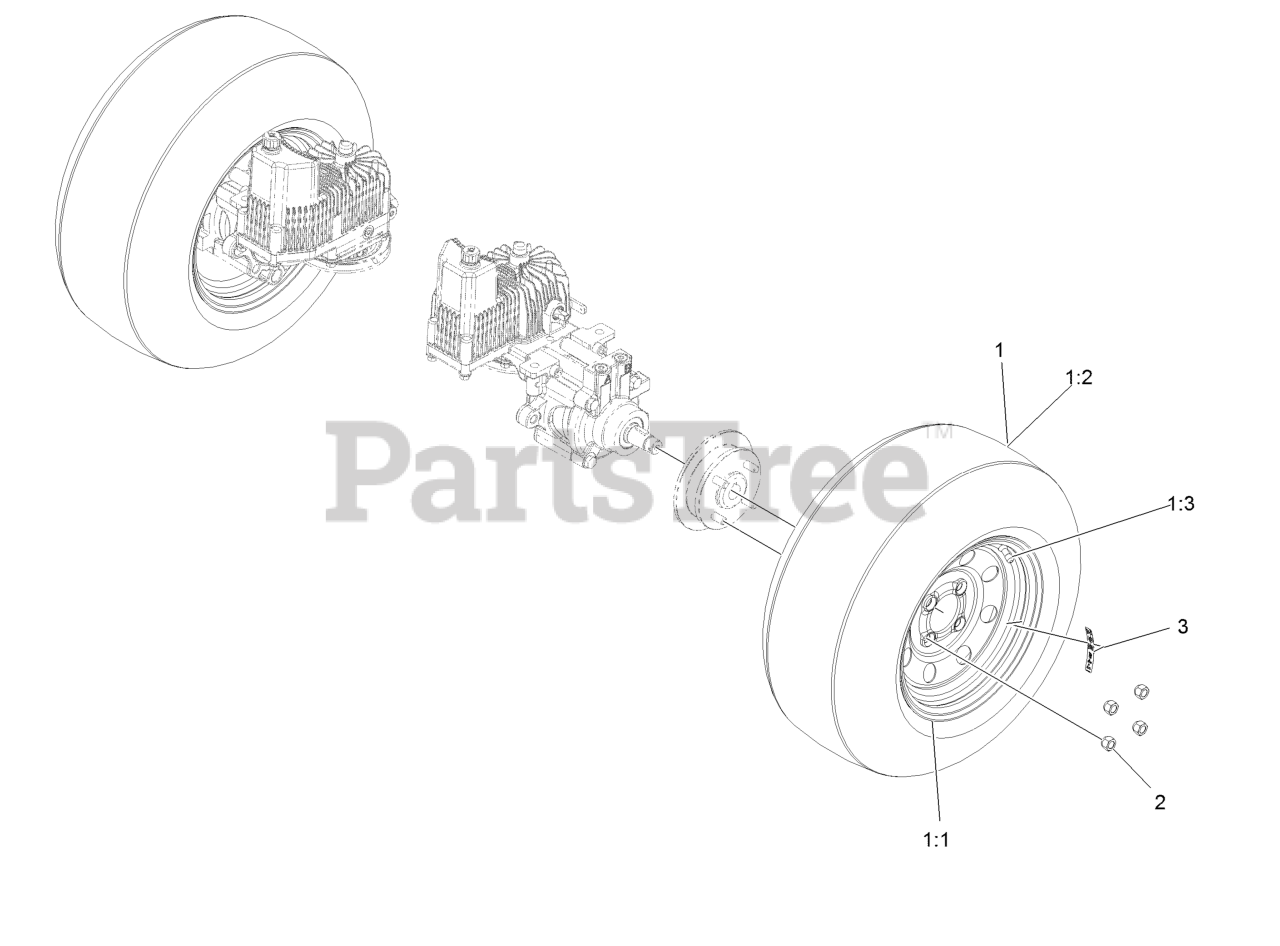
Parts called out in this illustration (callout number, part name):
1	Wheel And Tire ASM
1:1	ASM, Rim
1:2	Tire-Drive, 23X9.5-12
1:3	Stem-Valve
2	Nut-Lug 1/2-20
3	Decal-Torque, Wheel Hub Lug
